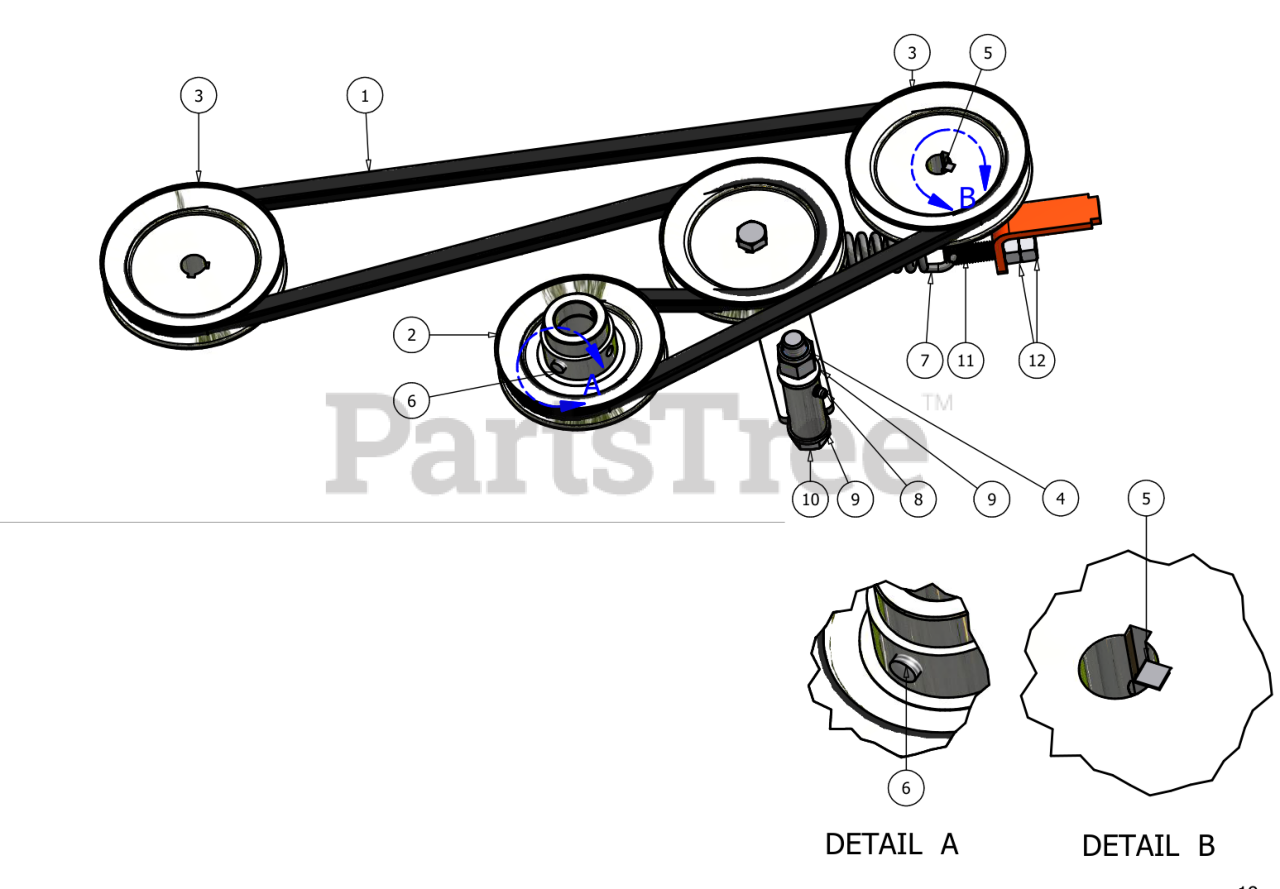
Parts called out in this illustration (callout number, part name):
2	4 3/4" Motor Pulley
3	5" Pump Pulley
4	5/8" Nylock Nut
5	5mm x 1 Key
6	3/8" Set Screw
7	Pump Idler Spring 6"
8	Grease Fitting (Drive-In Type)
9	.635 ID Plastic Washer
10	5/8" x 4" Hex Bolt
11	Spring Tensioner
12	1/2" Hex Nut
